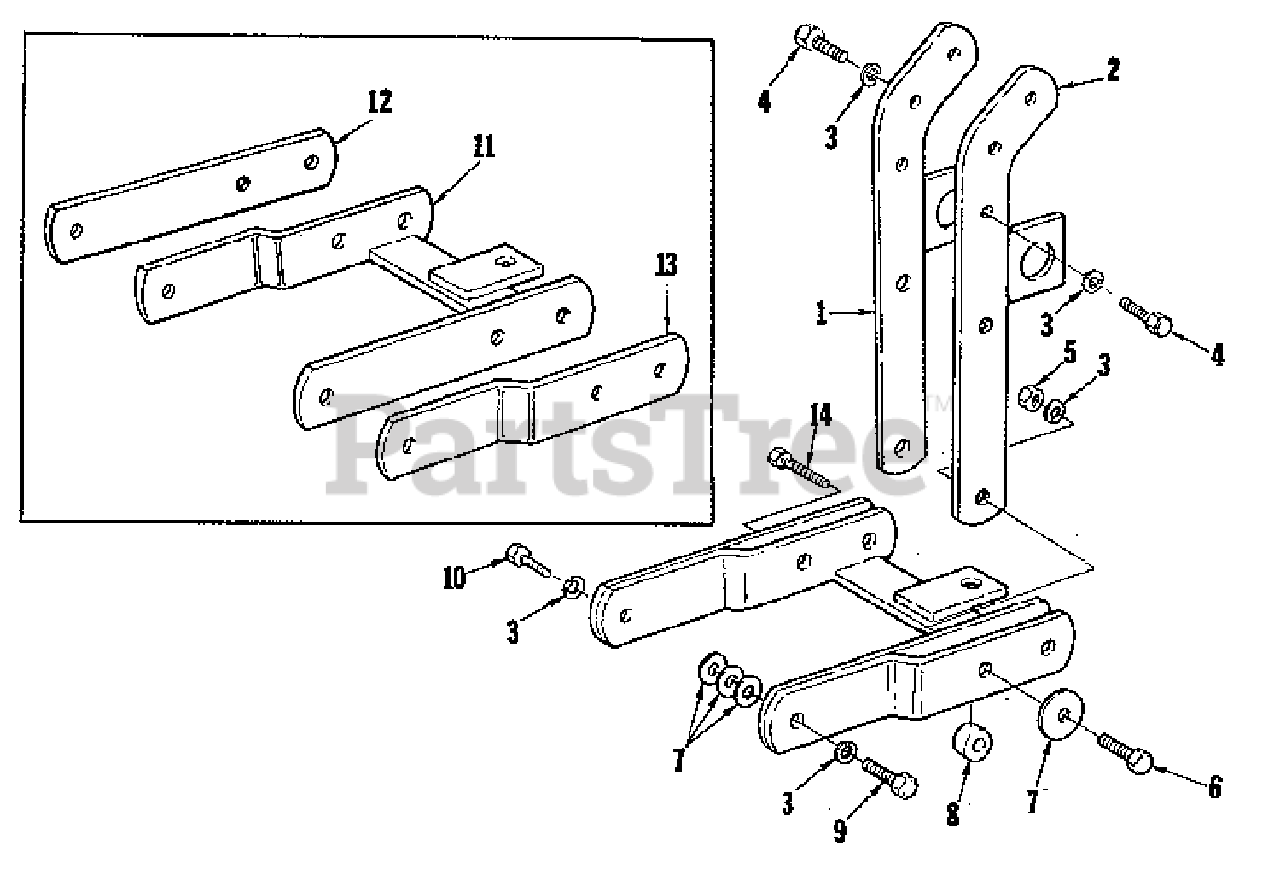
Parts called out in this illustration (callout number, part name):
1	ARM ASSEMBLY, L.H.
2	ARM ASSEMBLY, R.H.
3	WASHER, Lock
4	SCREW, Hex Head Cap
6	SCREW, Hex Head Cap, 7/16-14 x 1-3/4
7	WASHER, Flat
9	SCREW, Hex Head Cap, 7/16-14 x 1-1/2
10	SCREW, Hex Head Cap, 7/16-14 x 1-1/4
11	DRAWBAR ASSEMBLY
14	SCREW, Hex, 7/16-14 x 2
